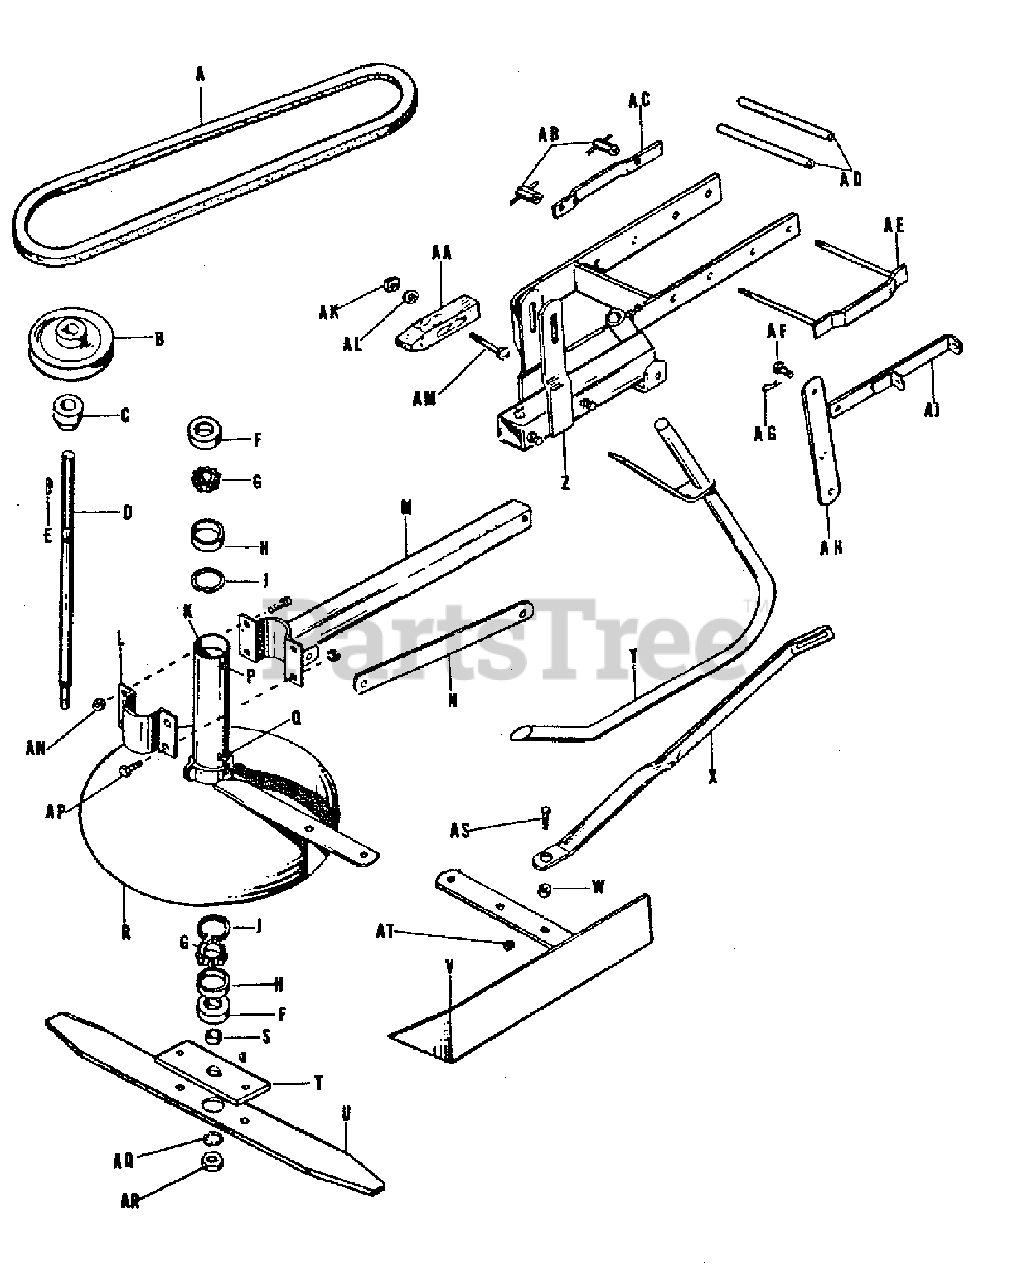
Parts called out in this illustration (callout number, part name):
A	V-BELT, 50"
B	PULLEY, Arbor
C	COLLAR, Arbor
E	ARBOR PULLEY KIT
F	SEAL, Oil
G	BEARING, Cone
H	BEARING, Cup
J	RING, Retaining
K	BEARING HOUSING, Arbor
L	CLAMP, Bearing Housing
M	TUBE ASSEMBLY, Clamp
N	CLUTCH, Lever Link
P	FITTING, Grease
Q	FITTING, Grease
R	DEFLECTOR ASSEMBLY
S	SPACER, Arbor
T	FLANGE, Arbor
U	BLADE (26")
U	BLADE (20")
V	GUARD ASSEMBLY, Chain
W	SPACER, Brace
X	BRACE, Deflector
Y	SHOE ASSEMBLY
Z	PUSH ARM ASSEMBLY
AA	SHOE, Brake
AC	HITCH, Side Plate
AE	CLAMP ASSEMBLY, Hitch
AF	BOLT, Clutch Lever
AG	SPRING, Clip
AH	LEVER, Clutch
AJ	GUIDE ASSEMBLY, Clutch Rod
AK	NUT, Full Hex, 3/8"-16 NC
AL	WASHER, Plain, 3/8"
AM	CARRIAGE BOLT, 3/8"-16 NC x 2" LG
AN	NUT, Hex Jam, 3/8"-16 NC
AP	CAPSCREW, 3/8"-16 NC x 3/4" LG
AQ	LOCKWASHER, Internal, 3/8"
AR	NUT, Hex Full, 5/8"-11 NC
AS	CAPSCREW, 5/16"-18 NC x 2" LG
AT	NUT, Hex Full, 5/16"-18 NC
